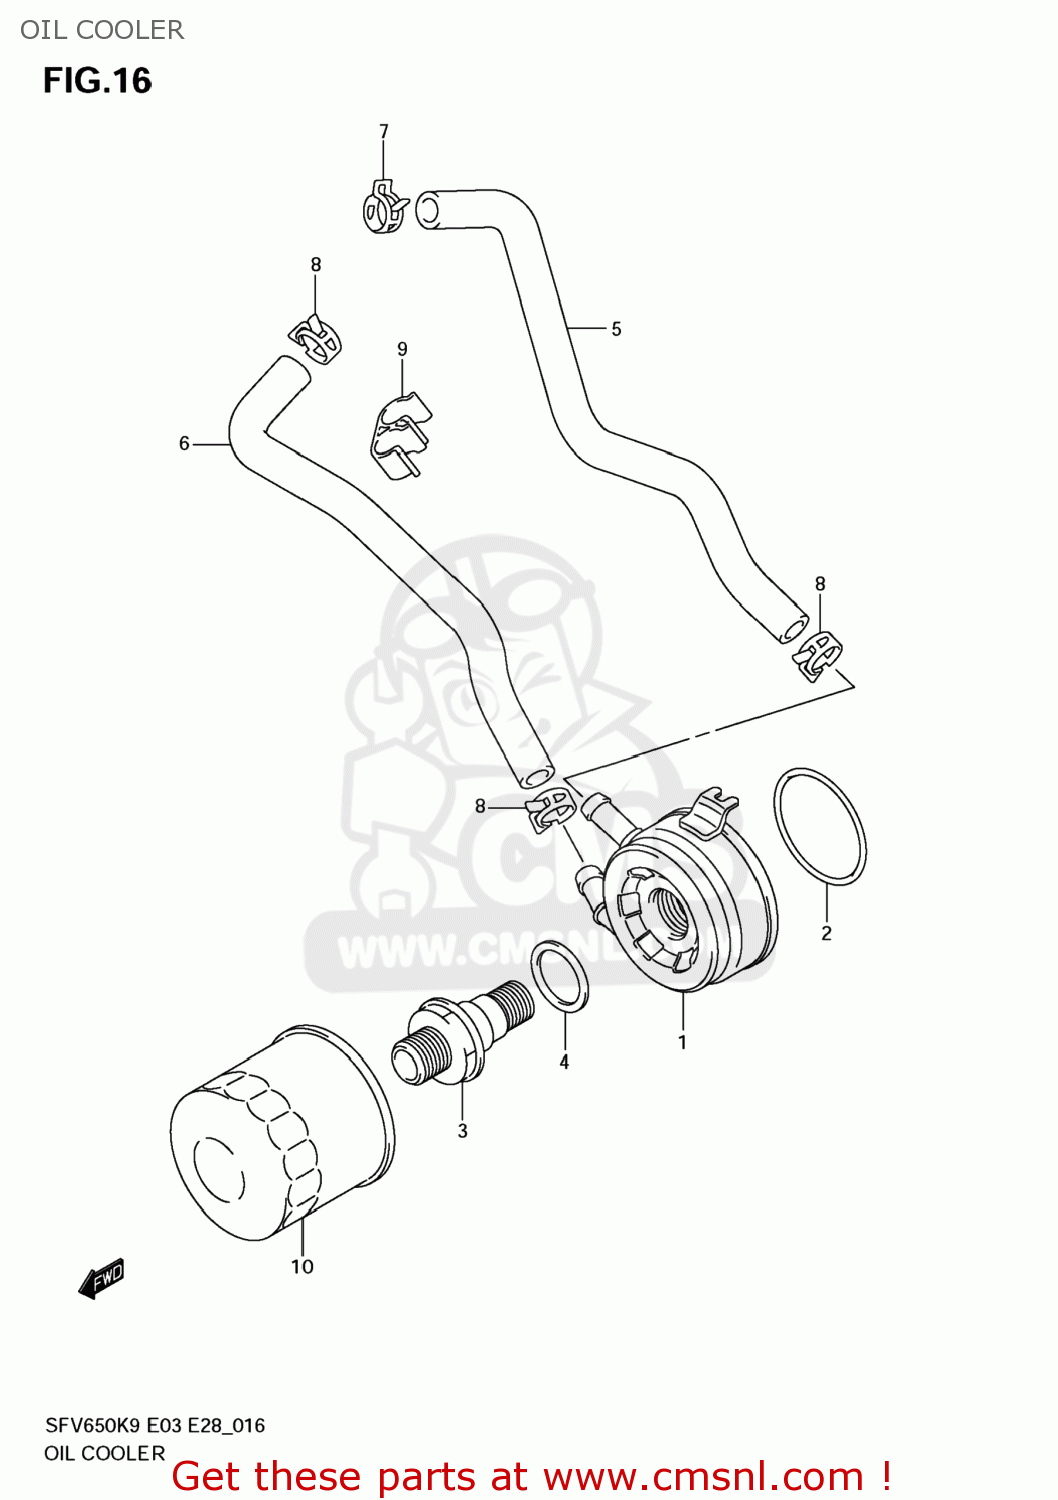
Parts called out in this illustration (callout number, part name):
1	COOLER ASSY,OIL
2	O RING(D:3.1,ID:54.5)
3	BOLT,OIL COOLER UNION
4	SHIM(25X34X0.7)
5	HOSE,OIL COOLER INLET
6	HOSE,OIL COOLER OUTLET
7	CLIP
8	CLIP
9	CLAMP
10	FILTER ASSY,EN
